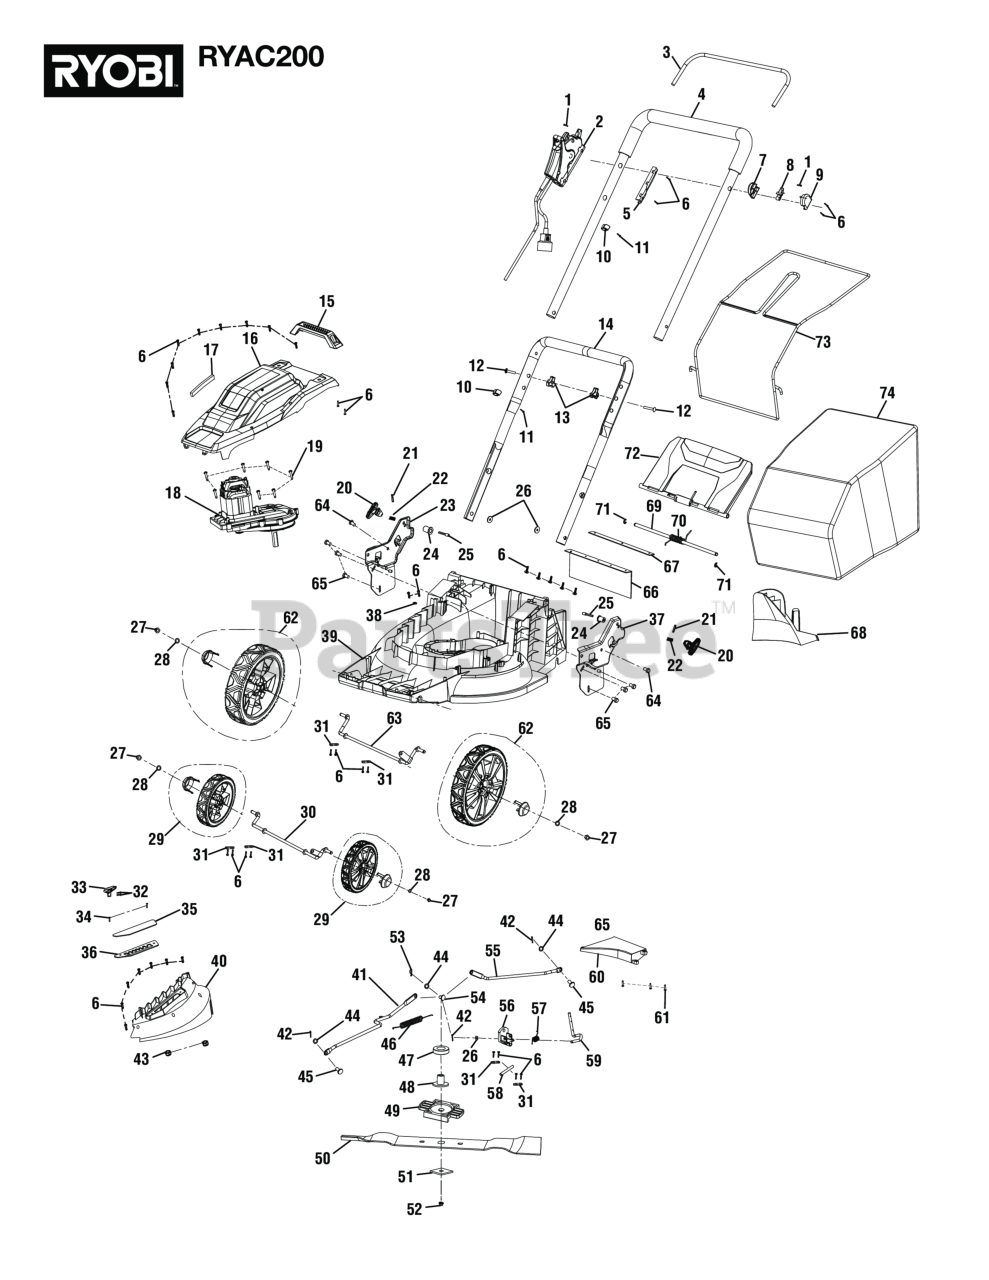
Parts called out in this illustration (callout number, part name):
1	Screw (M4 x 10 mm)
2	Switch Box Assembly
4	Upper Handle Assembly
5	Switch Box Cover
6	Screw (M4.2 x 15 mm)
7	Fixed Base (Left)
8	Support Frame (Left)
9	Fixed Cover (Left)
11	Screw with Washer (ST3 x 16 mm)
12	Shoulder Screw (M8 x 57 mm)
13	Triangle Rotary Knob
14	Lower Handle
15	Carry Handle
16	Top Housing
18	Motor Assembly
19	Screw (ST4.2 x 18 mm)
20	Adjusting Knob for Spring Pin
22	Detent Pin Spring
23	Handle Bracket (Right)
25	Handle Fixing Pin
26	Flat Washers (ID8 x OD16 x 1.6t)
27	Flange Nut (M8)
28	Flat Washers (ID8 x OD18 x 1.5t)
29	Front Wheel Assembly
31	Axle Press Plate
32	Screw (M4 x 12 mm)
33	Height Adjustment Handle
34	Screw (M5 x 18 mm)
35	Dust Proof Plate
36	Adjustment Lift Arm Bracket
37	Support Bracket (Left)
40	Adjustment Handle Cover
41	Forward Linkage
43	Hex Lock Nut (M5)
44	Washer (ID10 x OD18 x 0.8t)
46	Regulation Spring
47	Dust Proof Bearing
48	Blade Supporter
49	Blade Holder
51	Blade Spacer
52	Hex Nut (M10)
53	Butterfly Pin
54	Long Pin Shaft
55	Rear Linkage
56	Adjustment Support Frame
57	Spring (Adjustment Support Frame)
58	Axle (Adjustment Support Frame)
59	Height Adjustment Arm
60	Deck Insert
61	Screw (ST4.2 x 12 mm)
62	Rear Wheel Assembly
63	Rear Wheel Axle
64	Hex Bolt (M8 x 30 mm)
65	Screw (ST6.5 x 18 mm)
66	Rear Protective Guard
67	Pressing Plate (Rear Protective Guard)
69	Rear Door Axle
70	Spring (Rear Door)
71	Retaining Ring
73	Grass Bag Frame
